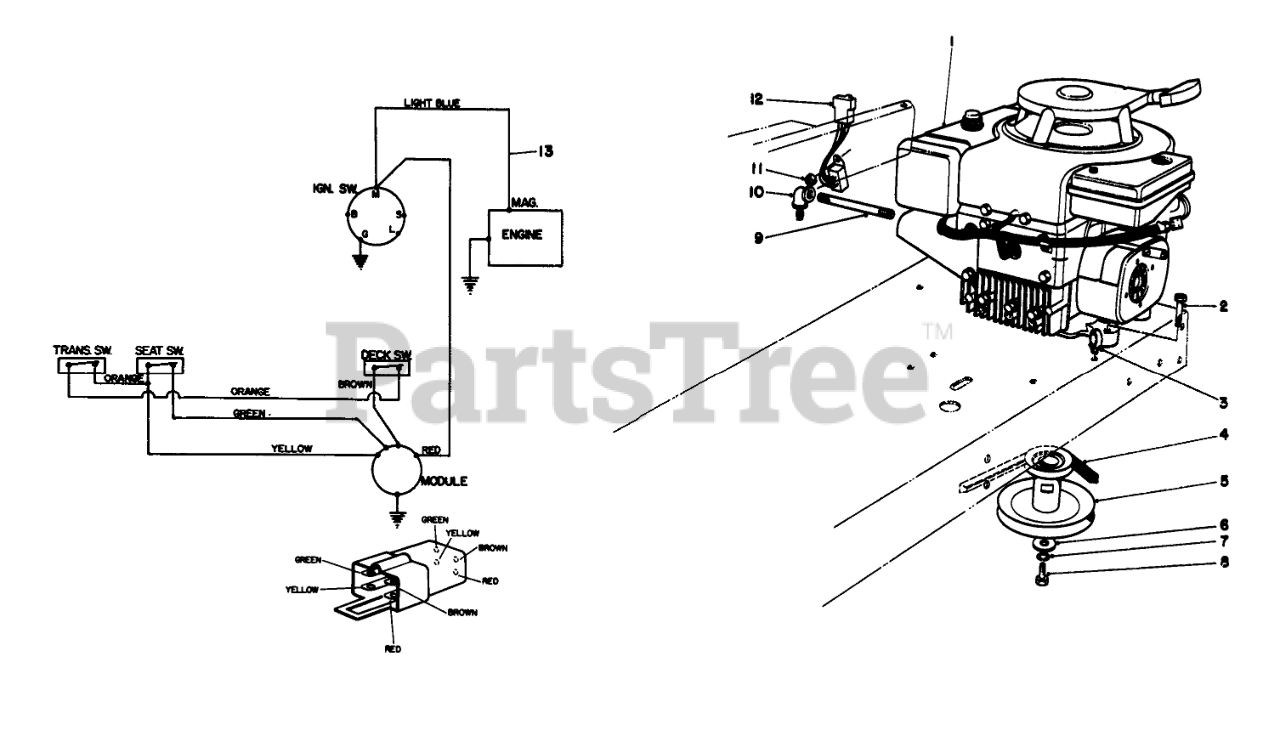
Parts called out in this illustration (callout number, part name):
1	Engine
2	SCREW-HH
3	Clip-Cable
4	V-BELT, TRACTION
5	PULLEY
6	WASHER
7	WASHER-LOCK
8	SCREW-HH
9	NIPPLE
10	ELBOW-90 DEGEE
11	NUT-LOCK, CONE
12	INTERLOCK MODULE
13	Wiring Harness
